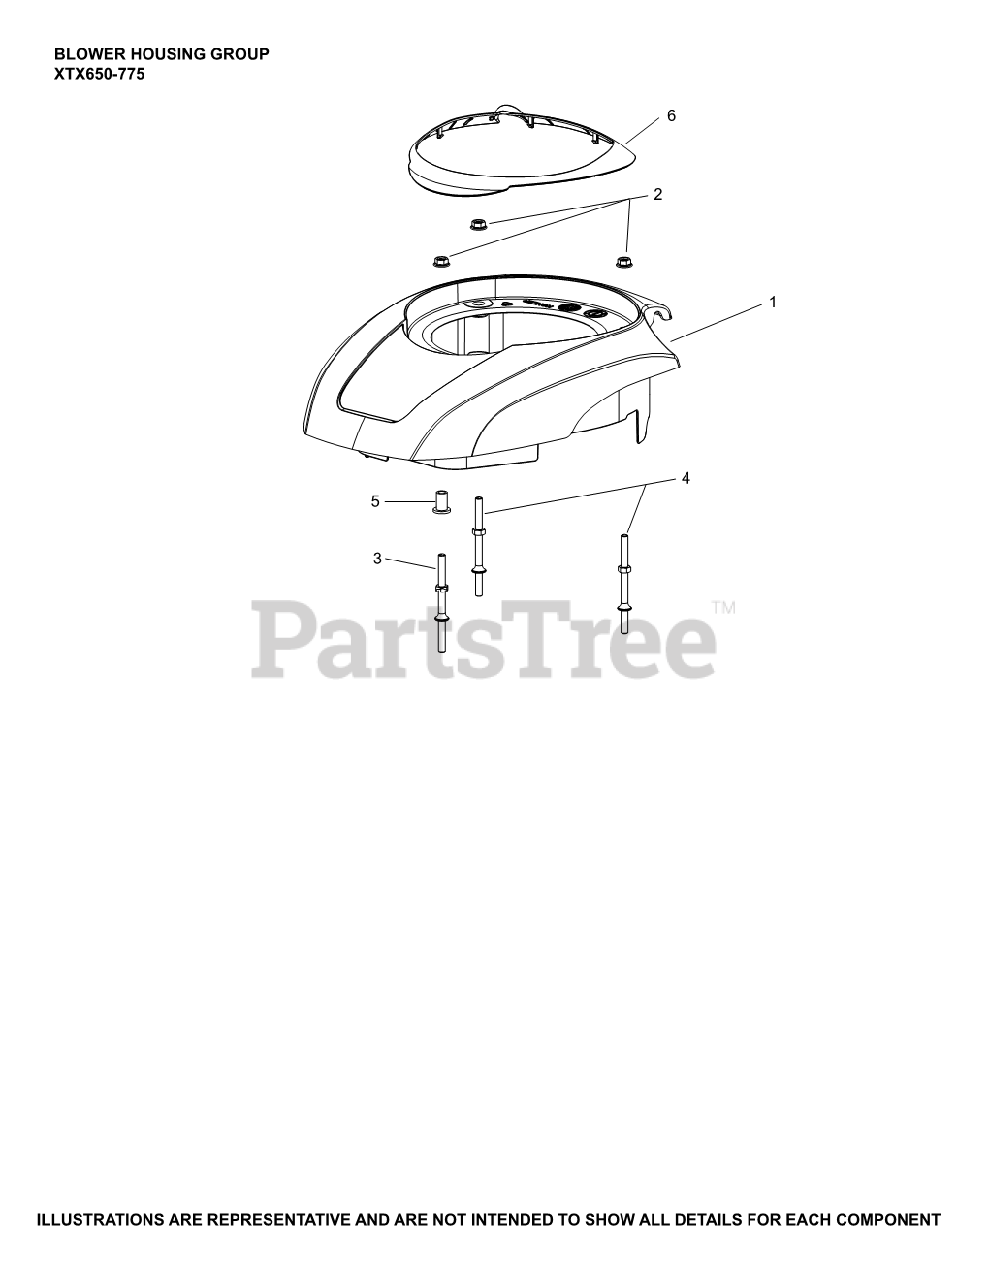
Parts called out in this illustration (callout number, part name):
1	COVER, ENGINE
2	NUT, HEX FLANGE (M6) - USE 14 100 16-S
3	STUD - (#1407225S)
4	STUD - (#1407226S)
